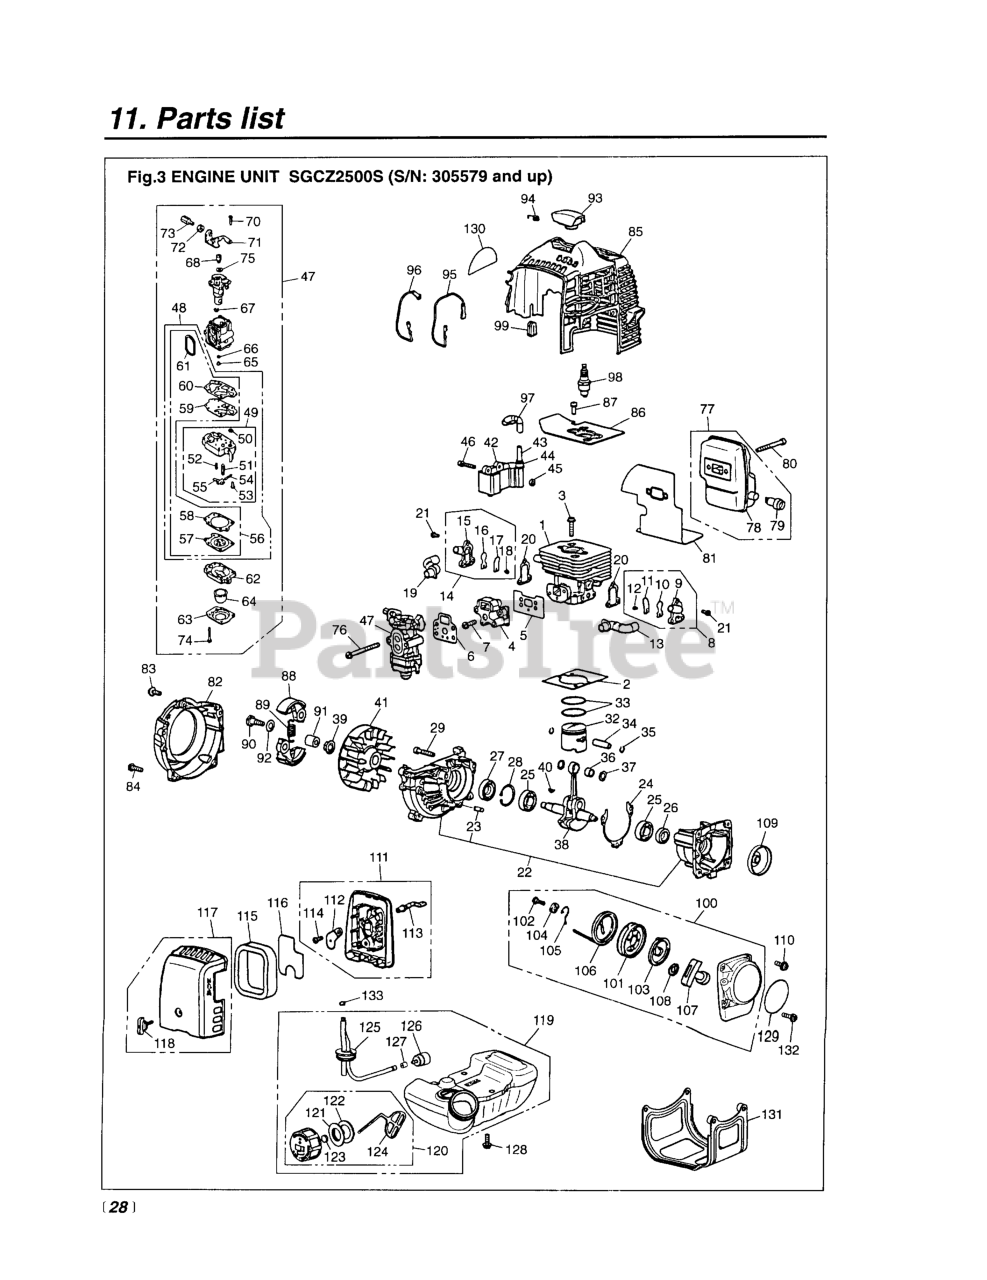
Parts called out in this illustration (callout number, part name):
1	CYLINDER (RPLS -12110)
2	GASKET, BASE
3	BOLT, M5 X 22
4	INSULATOR (RPLS. -13160/13161)
5	GASKET, INSULATOR
6	GASKET, CARBURETOR
7	SCREW, M5X20 (RPLS.1400-75510)
9	CASE VALVE
10	VALVE, REED
11	STOPPER
12	SCREW, M3 x 8
13	PIPE, AIR
16	VALVE, REED
17	STOPPER
18	SCREW, M3 x 8
19	PIPE, AIR (F)
20	GASKET, VALVE
21	SCREW
22	CRANKCASE-C
23	PIN
24	GASKET
25	BEARING
26	SEAL
27	SEAL, OIL (RPLS 1140-21220)
28	RING, SNAP, M28 x 1.2
29	BOLT, M5 X 30
32	PISTON
33	RING, PISTON
34	PIN
35	RING, SNAP (RPLS 1101-41320)
36	BEARING (RPLS 1140-41330)
37	WASHER
38	CRANKSHAFT COMPLETE
40	KEY
41	ROTOR
42	COIL ASSEMBLY
43	CORD
44	CAP
45	SPACER (RPLS -71260)
46	BOLT, M4 x 22
47	CARBURETOR (WYA-1-1)
48	REBUILD KIT
49	BODY-A
50	SCREEN
51	VALVE, INLET
53	SCREW
54	PIN
55	LEVER
56	KIT, GASKET (REPLACES-06020)
57	DIAPHRAGM
58	GASKET, DIAPHRAGM
59	DIAPHRAGM, PUMP
60	GASKET, PUMP
61	RING
62	BODY, PURGE
63	COVER, PUMP
64	PUMP, PRIMING
65	JET (REPLACES 4810-81250)
66	RING, O
67	RING
68	SWIVEL
70	SCREW
72	NUT, CABLE ADJUSTER
73	SCREW, CABLE ADJUSTER
74	SCREW
75	WASHER
76	SCREW, M5 x 60
77	MUFFLER ASSEMBLY
78	MUFFLER (REPLACES -15110)
79	ARRESTER
80	BOLT, M5 x 50
81	GASKET (RPLS T1501-15210)
82	COVER, FAN
83	SCREW
84	SCREW, M5X20 (RPLS.1400-75510)
85	COVER, ENGINE (RPLS -32110)
86	PLATE, CYLINDER
87	SCREW, M5 X 10
88	SHOE
89	SPRING
90	SCREW
91	WASHER
92	WASHER (RPLS -51241)
93	CAP (RPLS 4810-72110)
94	SPRING
95	CORD (BLACK)
96	CORD, EARTH (RED)
97	TUBE
99	GROMMET
100	RECOIL ASSEMBLY
101	REEL
102	SCREW
103	SPRING, SPIRAL
104	COLLAR
105	ARM
106	ROPE (REPLACES 4500-75160)
107	KNOB (RPLS -75420)
108	PLATE, STOPPER
109	PULLEY
110	SCREW
111	BODY ASSEMBLY
112	PLATE, CHOKE
113	LEVER, CHOKE
114	SCREW (REPLACES 50030272)
115	ELEMENT
116	SCREEN
117	COVER ASSEMBLY
118	KNOB (RPLS -82220)
119	TANK ASSY (RPLS-85001)
120	CAP ASSY (RPLS -85201)
121	HOLDER (REPLACES -85230)
122	PACKING
123	FILTER
124	STOPPER
125	PIPE COMPLETE
126	FILTER ASSY
128	SCREW
129	LABEL, RECOIL
130	LABEL, COVER
131	GUARD (RPLS 4810-31911)
132	SCREW, M5 x 25
133	CLIP
